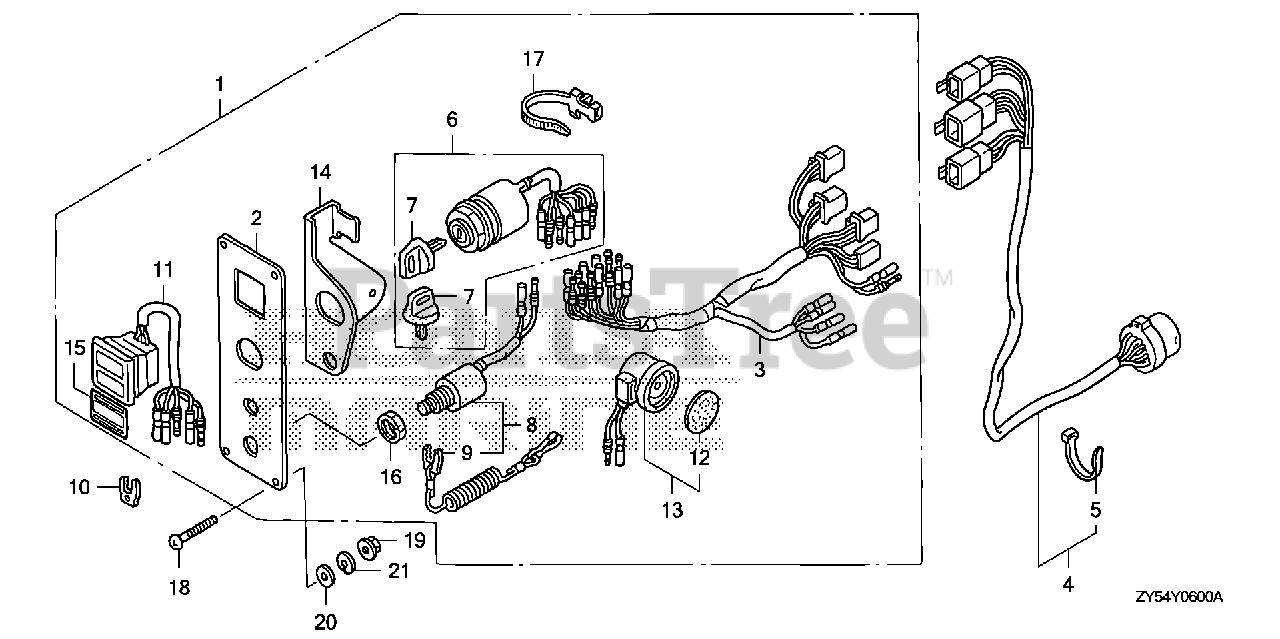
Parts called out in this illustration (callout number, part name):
1	PANEL ASSY., CONTROL (2-LED)
2	PANEL, CONTROL
3	HARNESS ASSY., SWITCH PANEL
4	CABLE ASSY., SWITCH PANEL
5	TIE, CABLE (NATURAL 2.4X92) Use up to Frame SN 1300359.
6	SWITCH ASSY., COMBINATION DUAL QTY = (2) (SINGLE)
6	SWITCH ASSY., COMBINATION (SINGLE) (DUAL)
7	KEY ASSY., COMBINATION SWITCH (35100-ZV5-003 ONLY) DUAL QTY = (4) (SINGLE)
8	SWITCH ASSY., EMERGENCY STOP
9	WIRE, EMERGENCY (SINGLE) (DUAL)
10	CLIP, EMERGENCY LOCK
11	LAMP ASSY., INDICATION (2-LED) DUAL QTY = (2) (SINGLE)
12	PLATE, TURN SIGNAL BUZZER DUAL QTY = (2) (SINGLE)
13	BUZZER, WARNING DUAL QTY = (2) (SINGLE)
14	BRACKET, BUZZER DUAL QTY = (2) (SINGLE)
15	MARK, SWITCH PANEL DUAL QTY = (2) (SINGLE)
16	NUT, HEX. (16MM) DUAL QTY = (2) (SINGLE)
17	BAND, WIRE HARNESS (150MM) (NATURAL) DUAL QTY = (2) (SINGLE)
18	SCREW, PAN (5X40) DUAL QTY = (8) (SINGLE)
19	NUT, FLANGE (5MM) DUAL QTY = (8) (SINGLE)
20	WASHER, PLAIN (5MM) DUAL QTY = (8) (SINGLE)
21	WASHER, SPRING (5MM) DUAL QTY = (8) (SINGLE)
